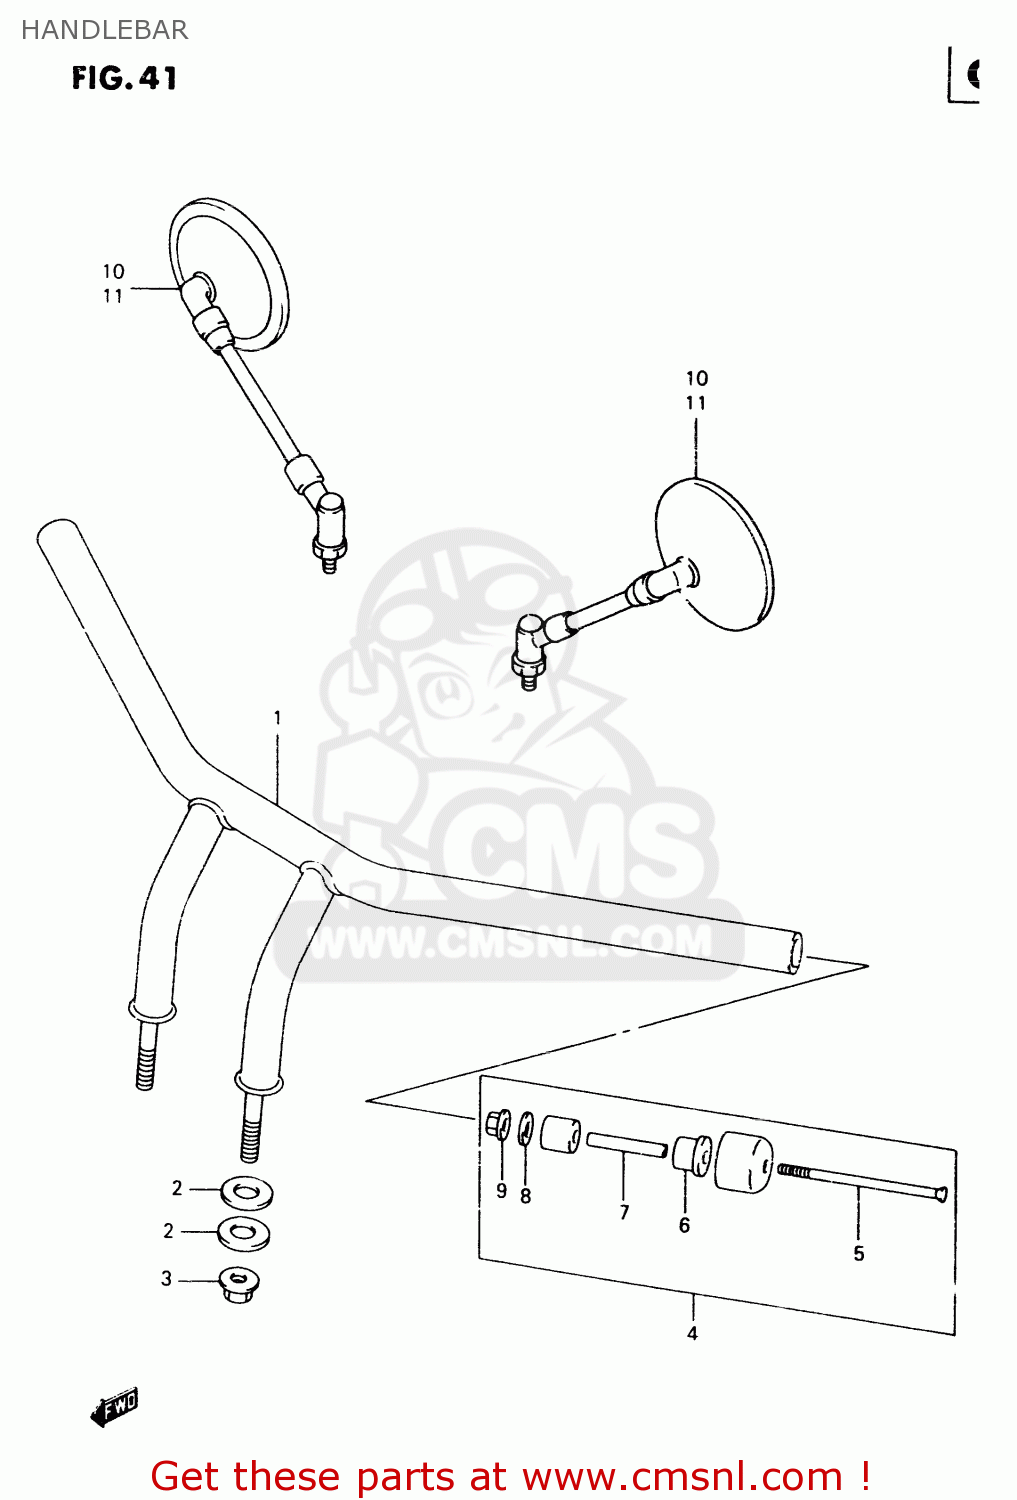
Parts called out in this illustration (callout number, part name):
1	HANDLEBAR
2	CUSHION,HANDLEBAR
3	NUT 12MM
4	BALANCER SET, HANDLEBAR
5	SCREW(6X110)
6	EXPANDER,HANDLE BALANCER NO.2
7	SPACER,EXPANDER
8	WASHER (6.5X18X2)
9	NUT
10	MIRROR ASSEMBLY,REAR VIEW
11	MIRROR ASSY,RR VIEW
